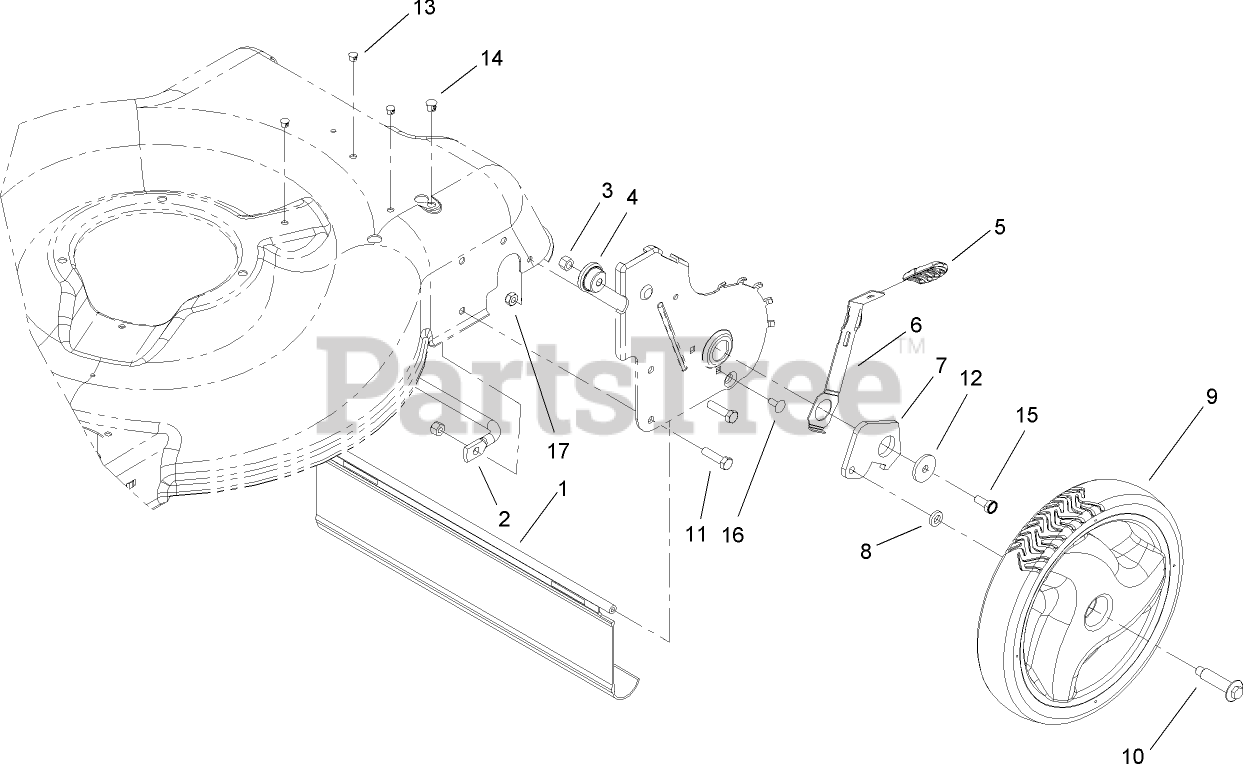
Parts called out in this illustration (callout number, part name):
1	SHIELD-TRAILING
2	BRACE-PLATE, HOC
3	NUT-HEX, SIDE DEFORM
4	BUSHING-MOUNT
5	KNOB-LEVER, HOC
6	ARM-11 INCH SPRING, REAR
7	ARM-PIVOT, REAR (LH)
8	WASHER-BOLT, WHEEL
9	11 INCH WHEEL ASM
10	BOLT-SHOULDER
11	SCREW-HH
12	WASHER-FLAT
13	PLUG-DOME
14	PLUG-DOME
15	SCREW-HH
16	SCREW-CARR
17	NUT-LOCK, NI
